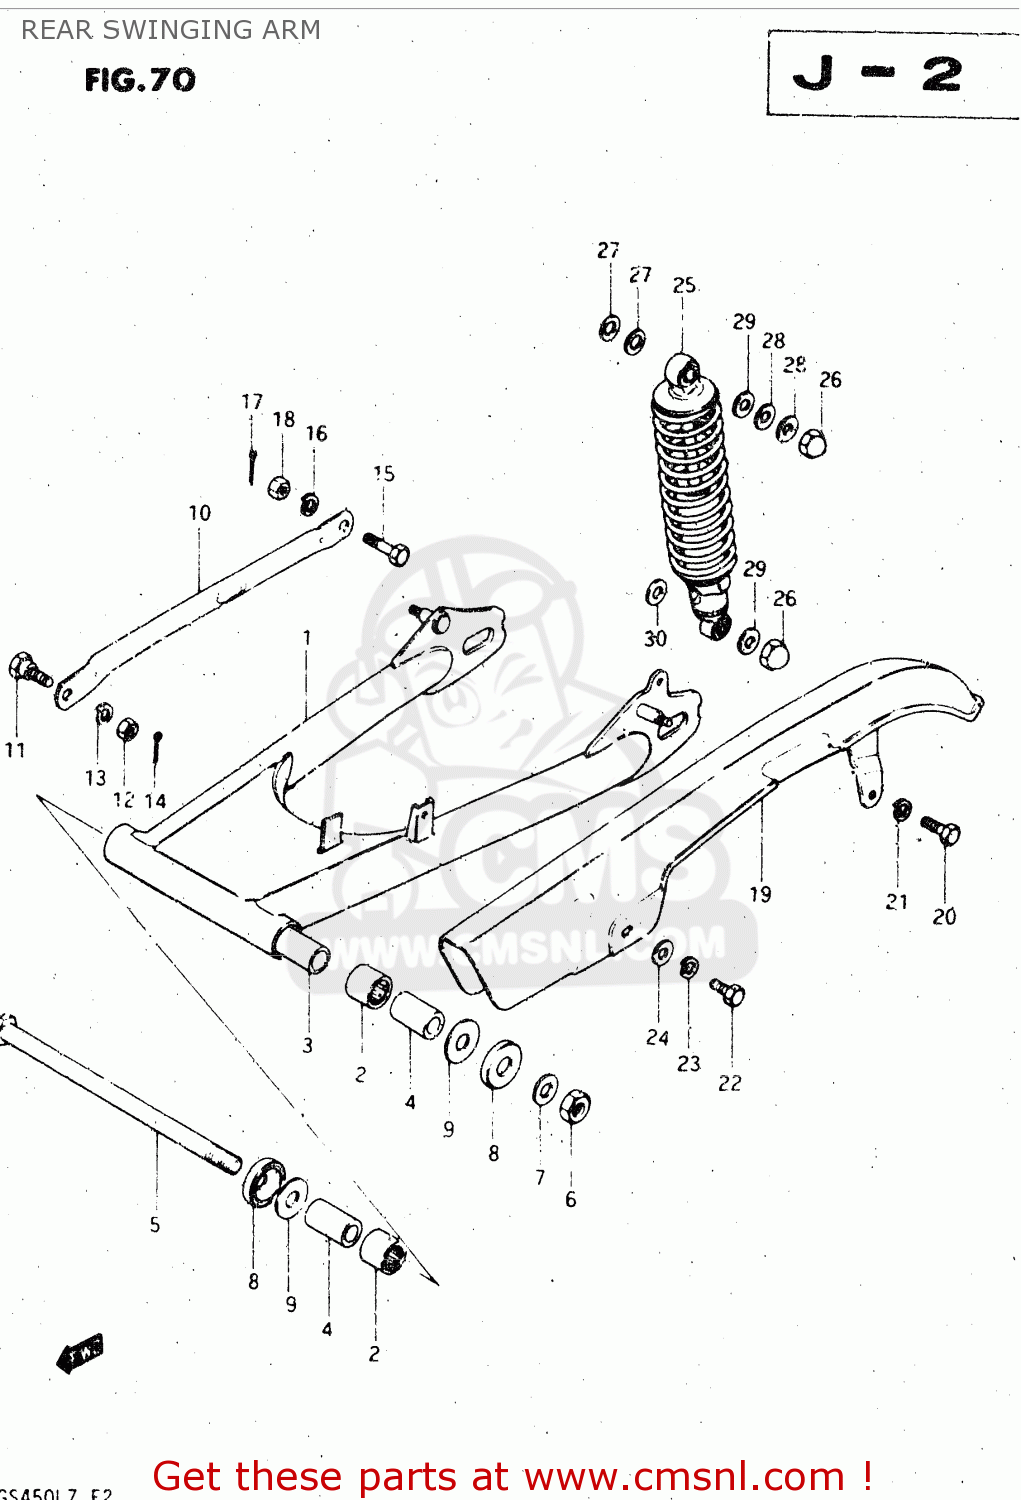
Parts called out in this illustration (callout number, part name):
1	ARM,REAR SWING
2	BEARING(22X29X30)
3	SPACER,SWINGINGARM CTR
4	SPACER,RR SWGARM PIVOT
5	SHAFT,REAR SWING ARM
6	NUT 14MM
7	WASHER
8	COVER,REAR SWING ARM DUST
9	WASHER(14.2X34X1)
10	LINK,REAR TORQUE
11	BOLT(10X24.5)
12	NUT
13	LOCK WASHER
14	PIN 20X20
15	BOLT(10X31)
16	LOCK WASHER
17	PIN 20X20
18	NUT
19	CASE,CHAIN
20	BOLT, UPPER
21	LOCK WASHER
22	BOLT
23	LOCK WASHER
25	ABSORBER ASSEMBLY,REAR SHOCK
26	NUT, LOWER LH
27	WASHER
28	WASHER
29	WASHER(10.5X24X3.2)
30	WASHER (12.5X24X1.6)
